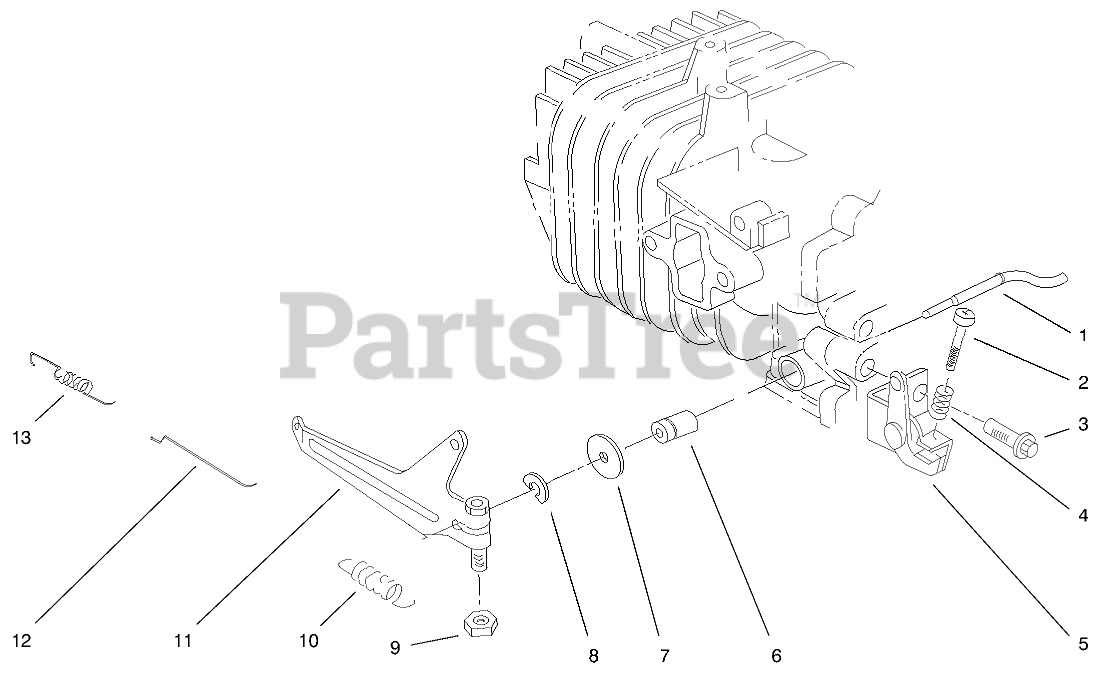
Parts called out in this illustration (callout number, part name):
1	SHAFT
2	SCREW
4	SPRING
5	GOV SPR BRKT
6	SEAL-OIL
7	WASHER
8	E-RING
10	GOV SPRING
11	GOVERNOR ARM
12	CARB ROD
13	CARB SPRING
